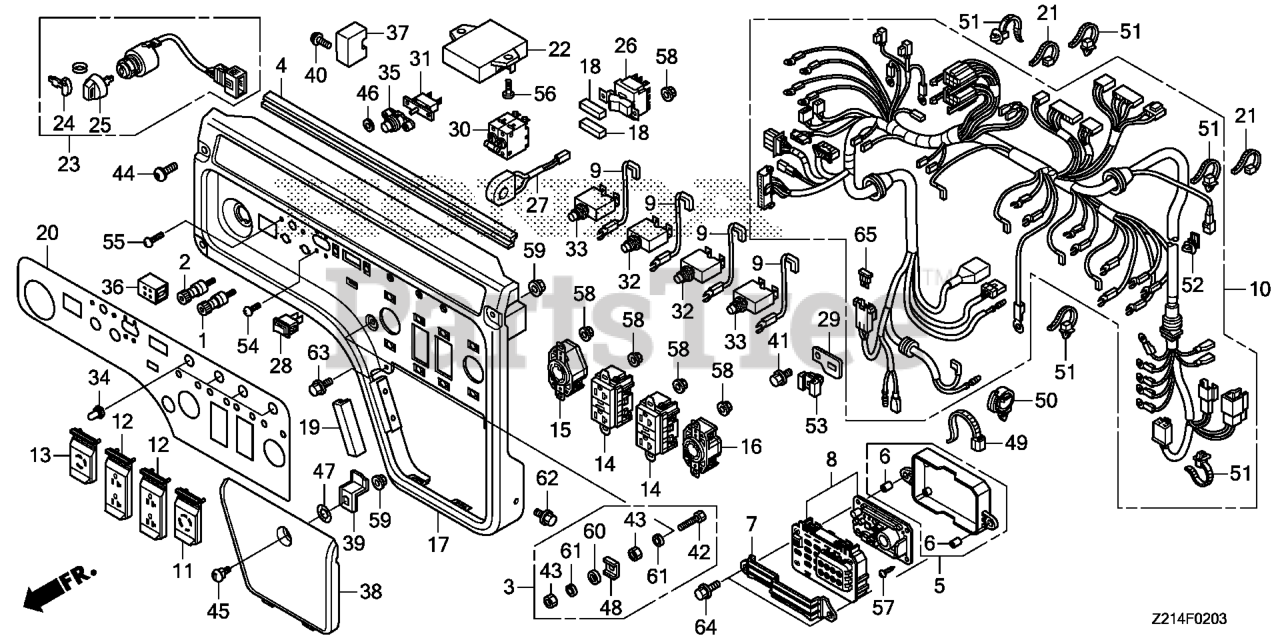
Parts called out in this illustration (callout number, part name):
1	TERMINAL, D.C. OUT (+)
2	TERMINAL, D.C. OUTPUT (-)
3	TERMINAL SET, GROUND
4	RUBBER, CONTROL PANEL
5	CASE, AUTOMATIC VOLTAGE REGULATOR (NOT AVAILABLE)
6	COLLAR, AUTOMATIC VOLTAGE REGULATOR CASE (NOT AVAILABLE)
7	COVER, AUTOMATIC VOLTAGE REGULATOR (NOT AVAILABLE)
8	COVER ASSY., AUTOMATIC VOLTAGE REGULATOR
9	SUB-WIRE ASSY. (A)
10	WIRE HARNESS ASSY., CONTROL (EM-AG)
11	COVER, RECEPTACLE (30A-125/250V)
12	COVER, RECEPTACLE (20A-125V)
13	COVER, RECEPTACLE (30A-125V)
14	RECEPTACLE (20A-125V) (GFCI)
15	RECEPTACLE (30A-125V)
16	RECEPTACLE (30A-125/250V)
17	PANEL, CONTROL *R280* (EM-AG) (POWER RED)
18	RUBBER, WATERPROOF
19	RUBBER, CONTROL PANEL (LOWER)
20	MARK, PANEL (EM-AG)
21	TIE, CABLE (C)
22	CONTROL UNIT, ENGINE (AG)
23	SWITCH ASSY., COMBINATION
25	KEY ASSY., COMBINATION SWITCH (BLACK)
26	SWITCH ASSY., VOLT CHANGE
27	SENSOR ASSY. (CT)
28	SWITCH, AUTO-THROTTLE (OTAX)
29	BRACKET, FUSE
30	BREAKER, CIRCUIT (21A)
31	PROTECTOR, CIRCUIT (D.C.)
32	PROTECTOR, CIRCUIT (20A)
33	PROTECTOR, CIRCUIT (30A)
34	COVER, CIRCUIT PROTECTOR
35	LENS ASSY., PROTECTOR
36	LED ASSY., INDICATER
37	BLUETOOTH UNIT (ISOLATE)
38	COVER (LOWER)
39	LOCK PLATE, COVER (LOWER)
40	BOLT, FLANGE (5X14)
41	BOLT, FLANGE (6X12) (CT200)
42	BOLT, HEX. (6X28)
43	NUT, HEX. (6MM)
44	BOLT, DISK (8X22) (TORX)
45	BOLT, MAINTENANCE LID LOCK
46	WASHER (4MM)
47	WASHER, WAVE (12MM)
48	RETAINER (6MM)
49	BAND, WIRE (95MM)
50	CLIP, WIRE HARNESS
51	CLIP, HARNESS BAND (145MM) (BLACK)
52	CLIP, CONNECTOR (DARK GREEN)
53	CLIP, CONNECTOR HOLDER
54	SCREW, PAN (3X5) (NOT AVAILABLE)
55	SCREW, PAN (3X16)
56	SCREW-WASHER (5X14)
57	SCREW, TAPPING (4X10) (PO)
58	NUT, FLANGE (4MM)
59	NUT, FLANGE (6MM)
60	WASHER, PLAIN (6MM)
61	WASHER, SPRING (6MM)
62	BOLT, FLANGE (6X10)
63	BOLT, FLANGE (6X14)
64	BOLT, FLANGE (6X16) Use from Engine SN 2056820.
65	FUSE, BLADE (20A)
